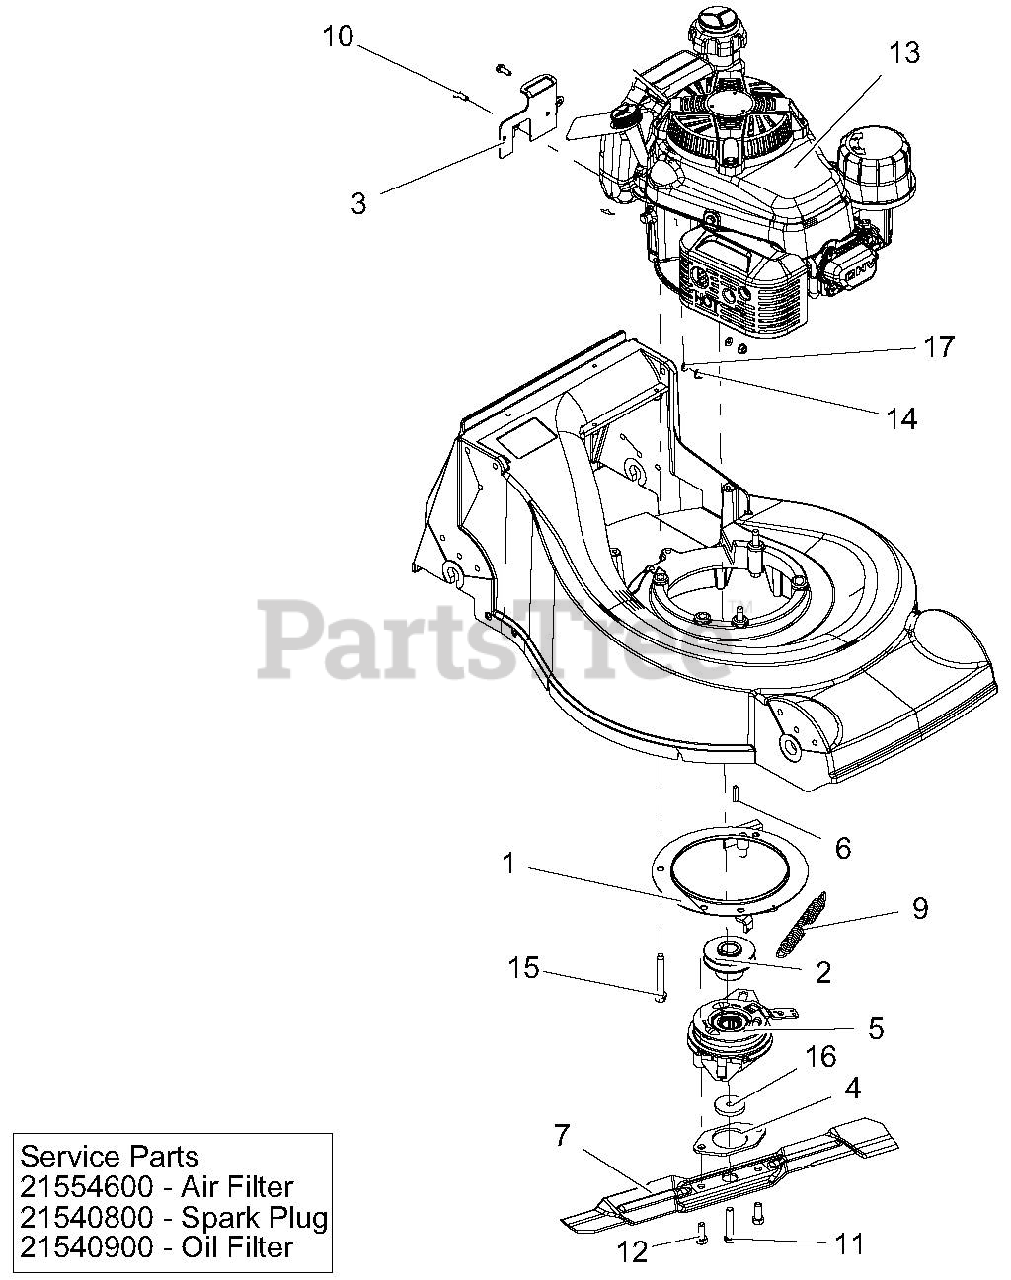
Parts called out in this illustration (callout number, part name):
1	WLDMT, PLATE -BBC
2	PULLEY, SP, KAWI, BBC
3	BRKT, FUEL TANK
4	SPCR, BBC BLADE
5	KAWASAKI, BBC
6	KEY 3/16 X 3/16 X 1
7	BLADE, MOWER 21" HIGH-LIFT
9	SPRG, EXTENSION BBC
10	BLT-HEX .25-20X.75 GR5 YWZC
11	BLT-HEX .38-24X2.00 YWZC GR8
12	BLT-HEX M10 X 1.5X20 GR5 YWZC
13	ENGINE, KAWASAKI BBC CARB
14	NUT, LK-TOP-FLG .25-20 YWZC
15	SCR-TAP.375-16X2.75 HWH TR YZ
16	WSHR-FL-STL .400X1.75X.250
17	WSHR-FL-STL.250X.562X.049YWZC
18	AIR FILTER
19	SPARK PLUG
20	OIL FILTER
